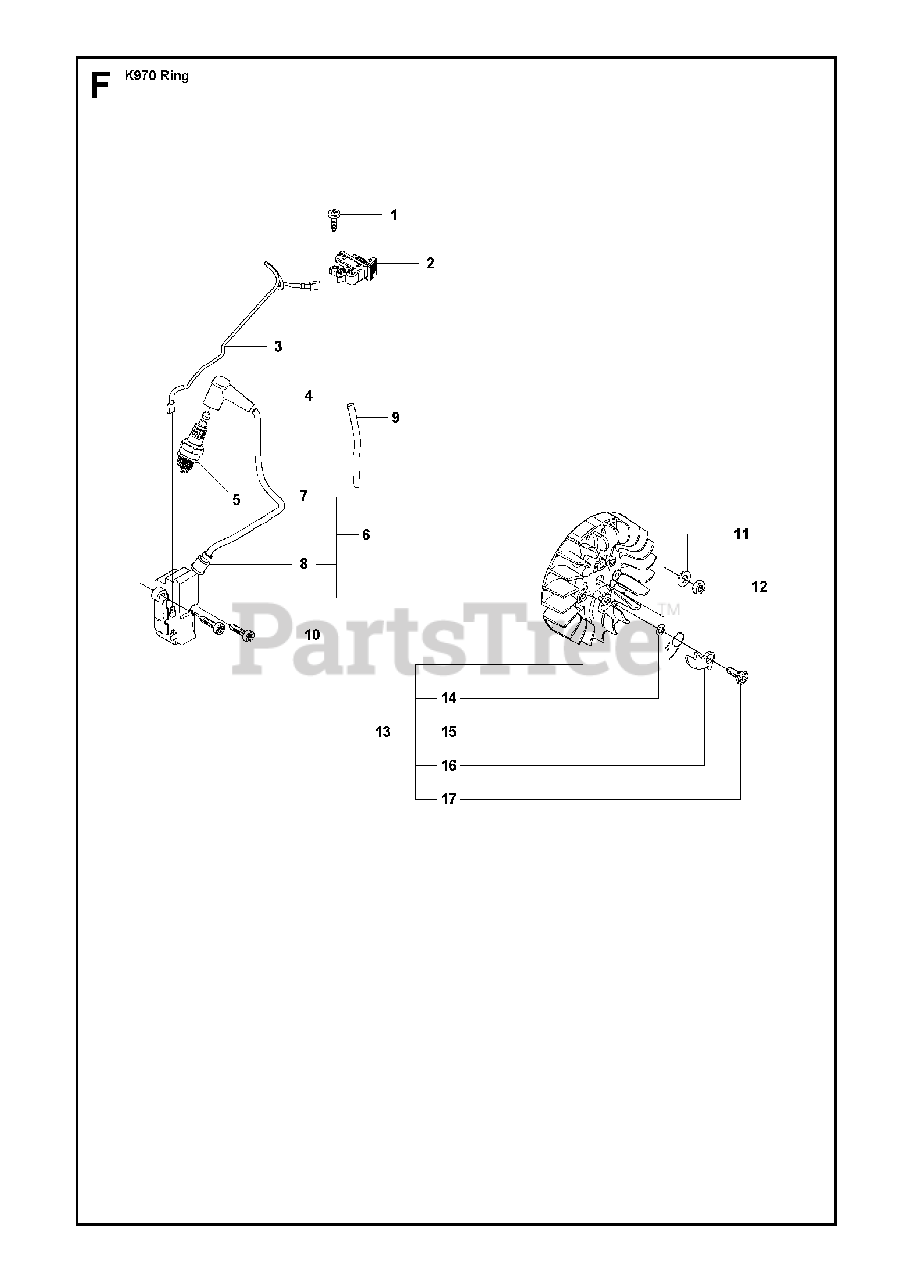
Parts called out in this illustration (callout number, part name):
1	SCREW CCRPANT
2	STOP SWITCH
4	SPARK PLUG CAP
6	IGNITION MODULEIncl. 7 - 8
7	IGNITION CABLE
10	SCREW ITXSCM
13	FLYWHEELIncl. 14 - 17
17	SCREW
